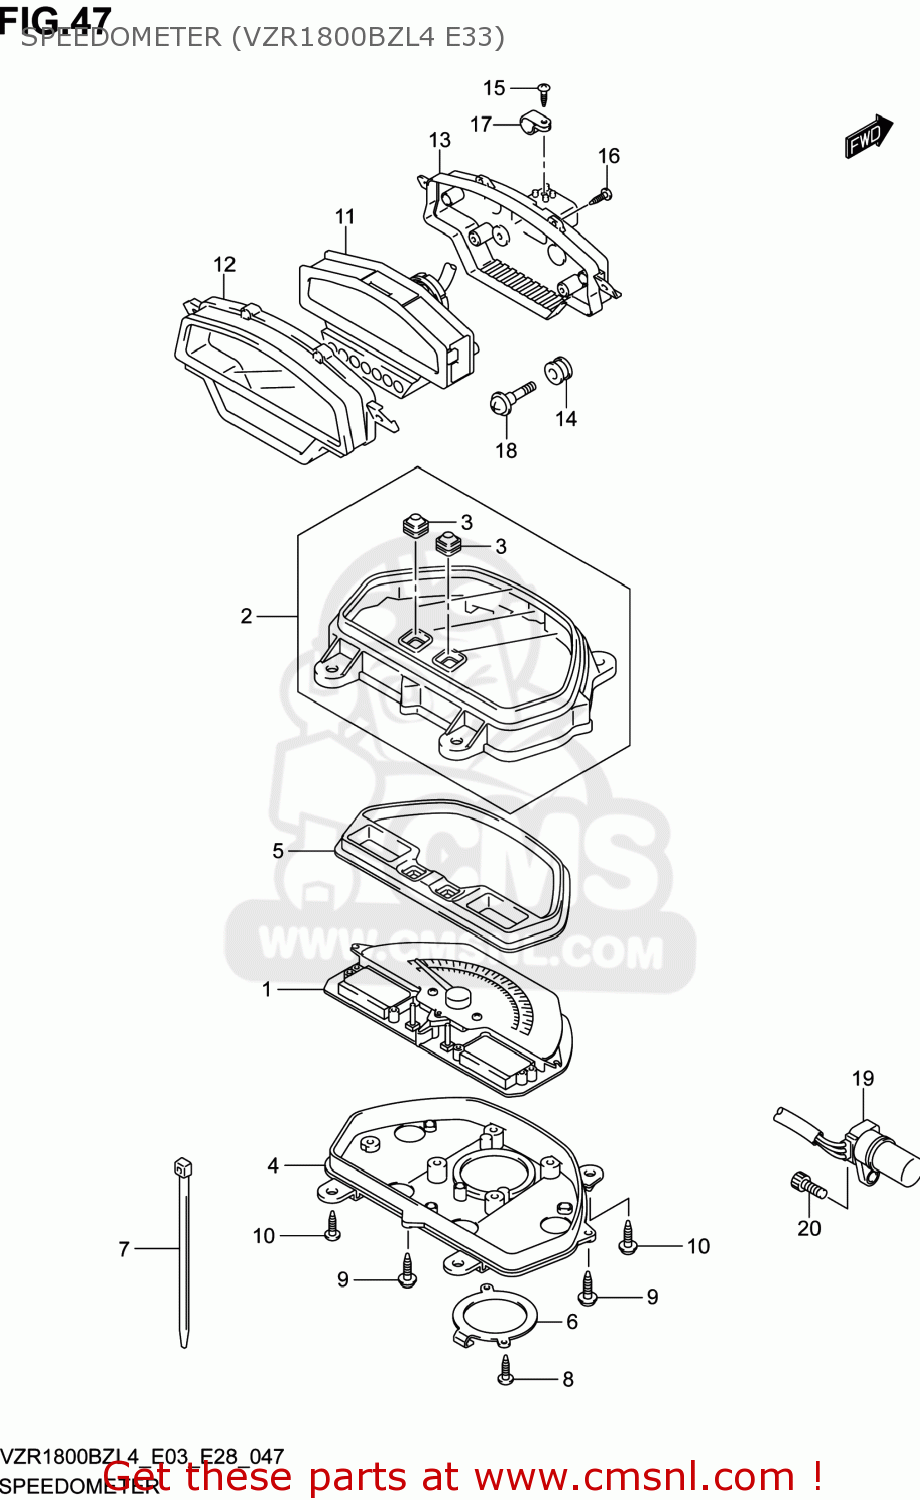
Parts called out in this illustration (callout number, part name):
1	SPEEDOMETER
2	UPR CASE ASSY
3	RUBBER,SWITCH
4	LWR CASE
5	REFLECTOR ASSY
6	BRACKET
7	CLAMP
8	SCREW(3X12)
9	SCREW(3X14)
10	SCREW
11	TACHOMETER ASSY
12	CASE ASSY,UPR
13	CASE ASSY,LWR
14	CUSHION
15	SCREW(4X14)
16	SCREW(3X16)
17	CLAMP
18	SCREW
19	SENSOR,SPEED
20	BOLT
